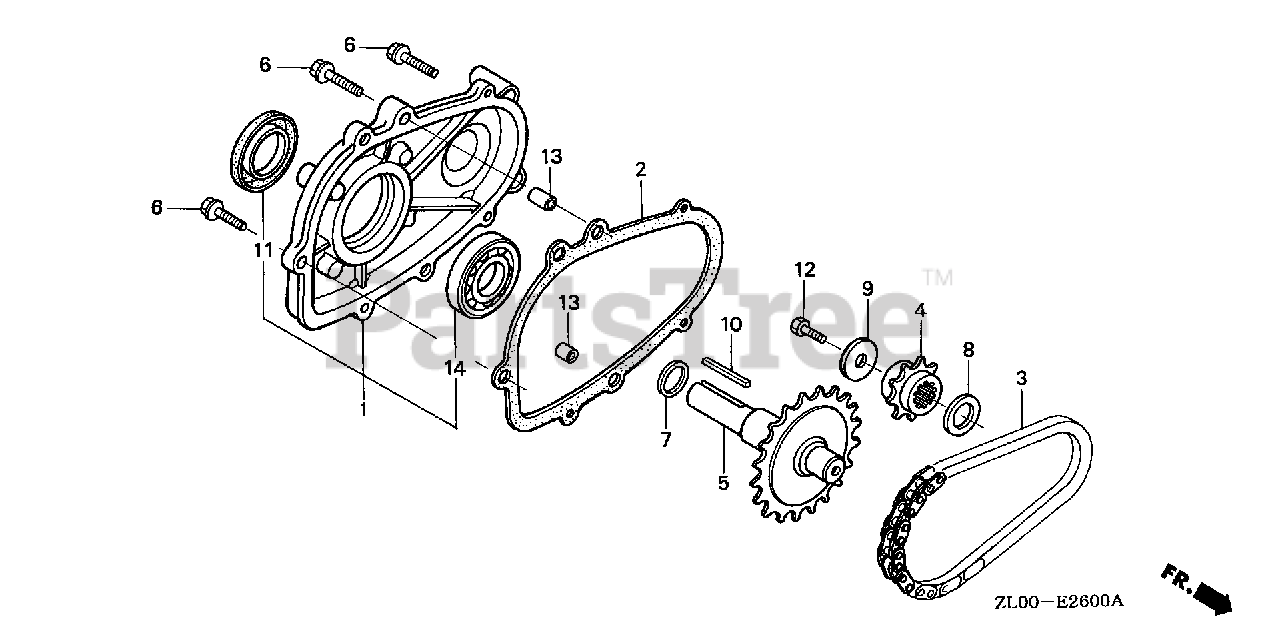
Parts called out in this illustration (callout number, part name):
1	COVER ASSY., CHAIN CASE
2	GASKET, CHAIN CASE COVER
3	CHAIN, P.T.O. DRIVE (DID317FM2-34LE)
4	SPROCKET, DRIVE (13T)
5	SHAFT, P.T.O. (26T)
6	BOLT, FLANGE (6X28) (CT200)
7	SPRING, THRUST
8	SPACER (20MM)
9	WASHER (8MM)
10	KEY (5X5X33) (YELLOW)
11	OIL SEAL (25X41X6)
12	BOLT, HEX. (8X25)
13	PIN, DOWEL (8X14)
14	BEARING, RADIAL BALL (6205)
